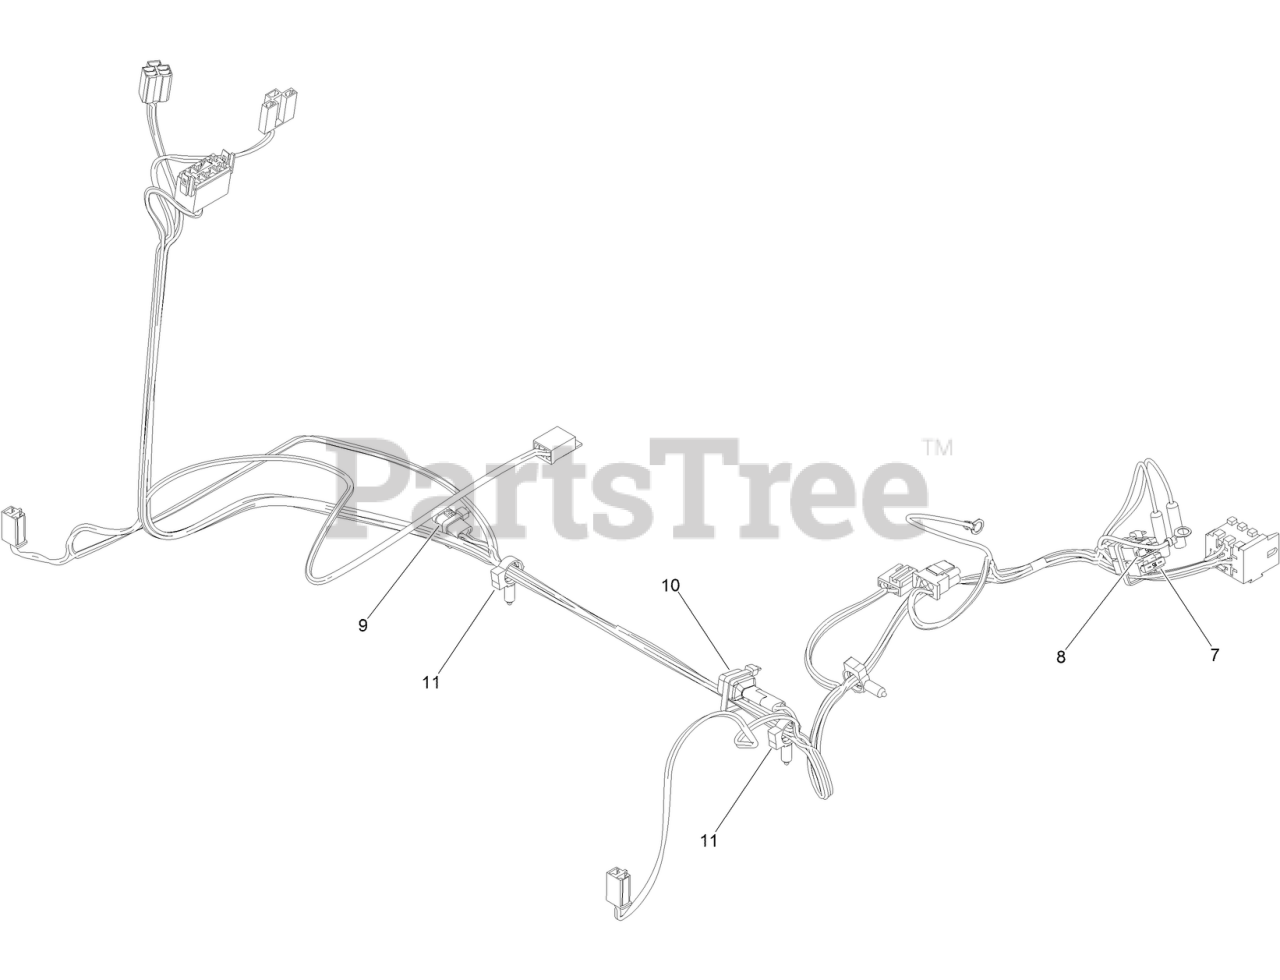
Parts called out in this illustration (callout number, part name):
7	FUSE-BLADE, 15 AMP
8	FUSE-BLADE, 25 AMP
9	CAP-OVER MOLD, 1M/1F
11	CLIP-TUBING, HARNESS
